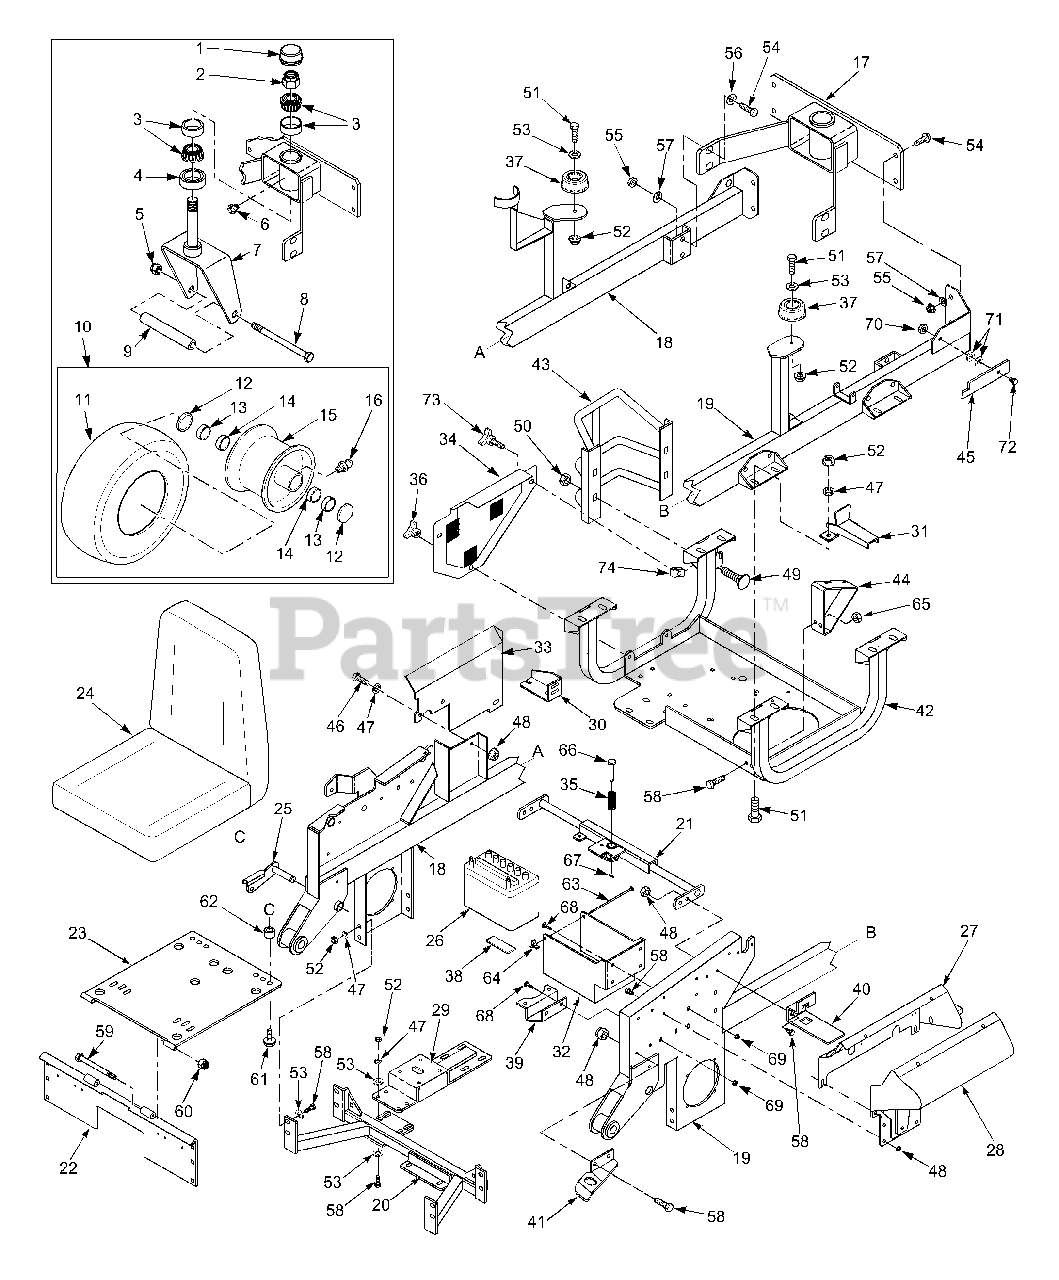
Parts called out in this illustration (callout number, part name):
1	Cap, Grease
2	Nut, Elastic Jam 1.0-14
3	Bearing, 1.0 Diameter
4	Seal, 2.00 OD x 1.625 ID
5	Nut, Elastic Stop 5/8-11
6	Plug, 1/4-28
7	Yoke, Wheel
8	Bolt, Hex Head 5/8-11 x 9.5"
9	Spacer
10	Wheel Assy, 16 x 6.5-8
11	Tire, 16 x 6.5-8
12	Seal, Wheel Bearing
13	Cone, Bearing
14	Cup, Bearing
15	Rim Assy,
16	Fitting, Grease
17	Weldment, Rear Caster Support
18	Weldment, Main Frame RH
19	Weldment, Main Frame LH
20	Weldment, Axle Support
21	Weldment, Seat Support
22	Plate, Front Crossmember
23	Weldment, Seat Plate
24	Seat Assy.
25	Weldment, Deck Stop
26	Battery
27	Cover, Instrument Panel
28	Rear, Instrument Panel
29	Weldment, Gearbox Support
30	Plate, Gearbox Upper
31	Mount, Fuel Tank Rear
32	Box, Battery
33	Heatshield
34	Cover, PTO Clutch
35	Spring, Seat
36	Knob with Stud
37	Pad, Rubber Hopper Rest
38	Pad, Rubber
39	Bracket, Hydraulic Filter Mounting
40	Bracket, Fuel Tank Front
41	Catch, Cutter Deck
42	Weldment, Engine Deck
43	Weldment, Muffler Guard
44	Bracket, Oil Cooler
45	Rod, Hopper Prop
46	Bolt, Hex Head 3/8-16 x 1"
47	Lockwasher 3/8"
48	Nut, Serrated Flange 3/8-16
49	Bolt, Carriage 7/16-14 x 1"
50	Nut, Serrated Flange 7/16-14
51	Bolt, Hex Head 3/8-16 x 1.5"
52	Nut, Elastic Stop 3/8-16
53	Flatwasher, 3/8"
54	Bolt, Hex Head 1/2-13 x 1.5"
55	Nut, Elastic Stop 1/2-13
56	Flatwasher 1/2"
57	Lockwasher 1/2"
58	Bolt, Hex Head 3/8-16 x 1.25"
59	Bolt, Hex Head 5/16-18 x 3.5"
60	Nut, Elastic Stop 5/16"
61	Bolt, Capscrew 5/16-18 x .75"
62	Spacer
63	Bolt, Carriage 1/4-20 x 6"
64	Wing Nut, 1/4-20 x .75"
65	Nut, Elastic Stop 3/8-16
67	Roll Pin, Spring 5/32 x .75"
68	Bolt, Carriage 5/16-18 x .75"
69	Nut, Serrated Flange 5/16-18
70	Nut, Elastic Stop 5/16-18
71	Washer
72	Bolt, Hex Head 5/16-18 x 1"
73	Knob, w/stud 3/8-16 x 1-1/4"
74	U-Nut, 3/8-16
